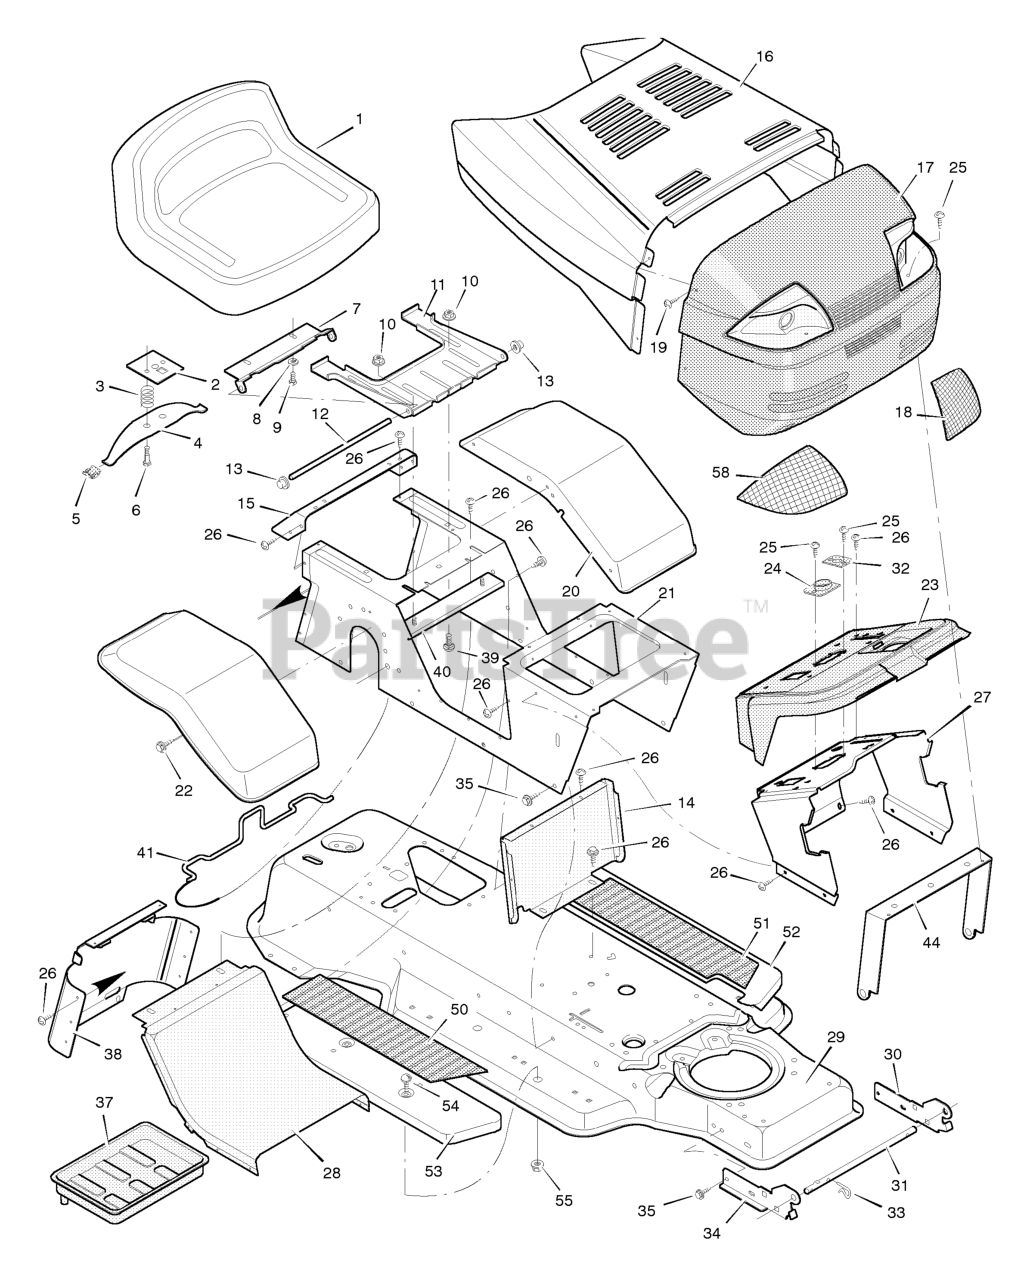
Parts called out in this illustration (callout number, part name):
2	Plate Assembly, Switch
3	Spring, Compression
4	Spring, Seat
5	Glide, Spring
6	Bolt, Shoulder
7	Support, Seat
8	Lockwasher
9	Bolt, Hex
10	Locknut, Flange
11	Bracket, Pivot
12	Rod, Pivot
13	Cap, Push On
14	Insert, Front
15	Fender, Apron
17	Grille Assembly
18	Lens, Left
21	Console Assembly
23	Dash Panel
24	Bearing, Steering
26	Screw
27	Support, Dash
28	Insert, Rear
29	Frame Assembly
30	Bracket, Left Grille
31	Rod, Pivot
32	Bearing
33	Pin, Hair
34	Bracket, Right Grille
37	Tray, Battery
38	Cap, Console
39	Bolt
40	Channel Assembly
41	Clamp, Battery
44	Brace, Grille
45	Washer
46	Bolt, Hex
50	Mat, Right
51	Mat, Left
52	Running Board, Left
53	Running Board, Right
54	Bolt, Carriage
55	Nut, Flange
58	Lens, Right
